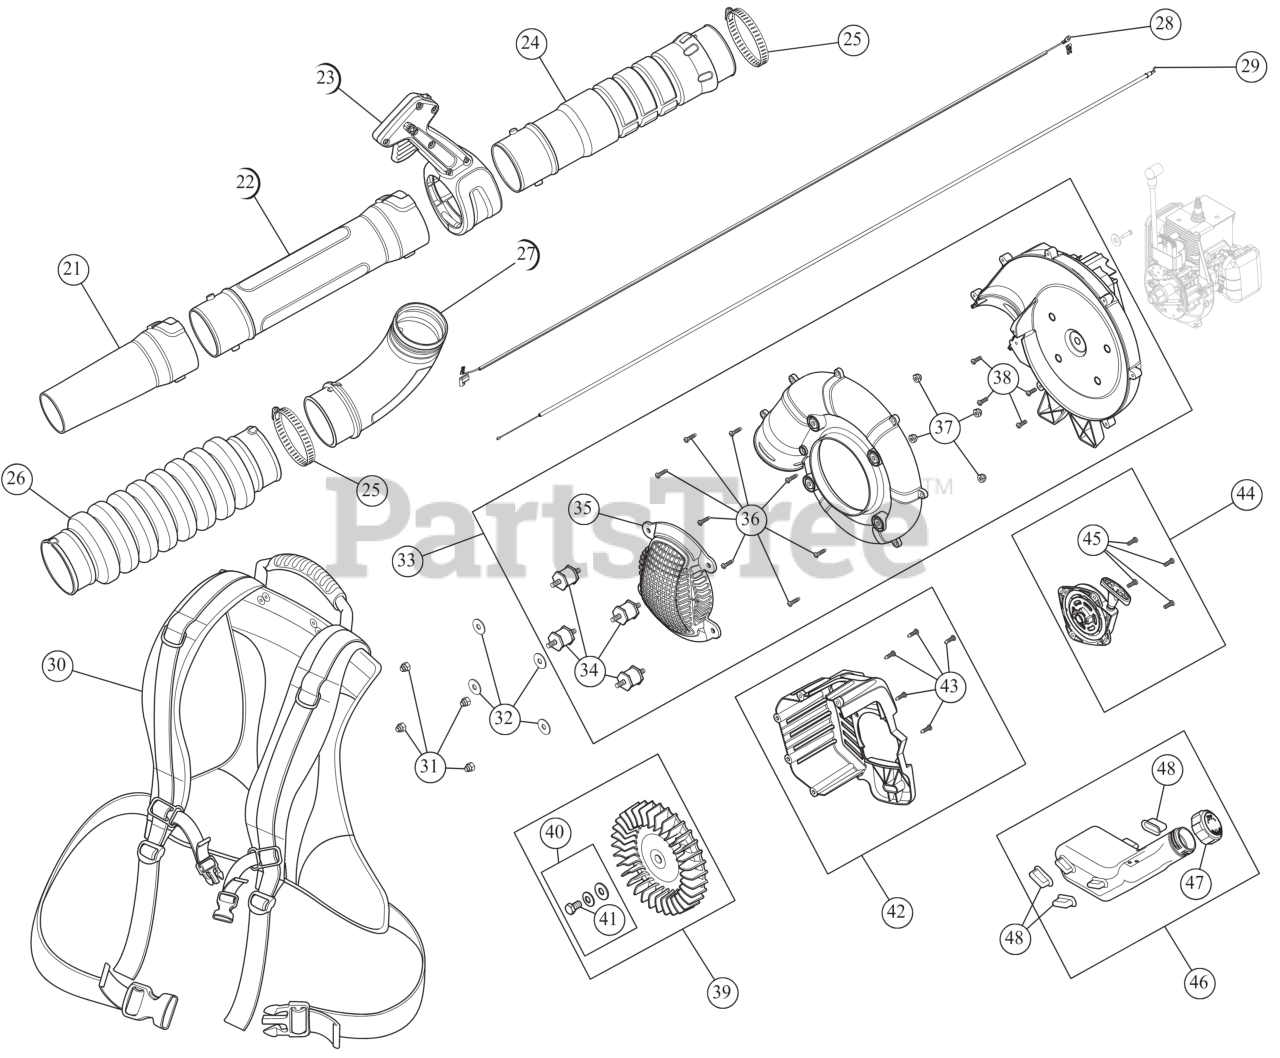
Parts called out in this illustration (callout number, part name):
21	NOZZLE BKPK CUB
22	TUBE LOWER BKPK
23	GRIP ASSEMBLY 4CYBKPK
24	TUBE UPPER BKPK
25	HOSE CLAMP
26	TUBE BKPK
27	TUBE ELBOW BKPK
28	LEAD WIRE
29	THROTTLE CABLE
30	HARNESS
31	HEX ACORN NUT
32	WASH, FLAT SPECIAL
33	IMPELLER HOUSING BPK
34	INSULATOR MOUNT
35	INTAKE COVER AC4
36	SCREW, #8-16X.750 PH
37	NUT 1/4-20 NYLOC
38	SCREW:10-32X.562:#8P
39	IMPELLER ASSEMBLY
40	HDWE-IMPELLER
41	BOLT, HEX HD 3/8-2
42	ENGINE COVER (LIB RED)
43	SCREW, #8-16X.750 PH
44	STARTER ASSEMBLY RR
45	SCREW:10-32X.562:#8P
46	FUEL TANK ASSEMBLY
47	ASSEMBLY, FUEL CAP (RED TOP)
48	FUEL TANK PADS
